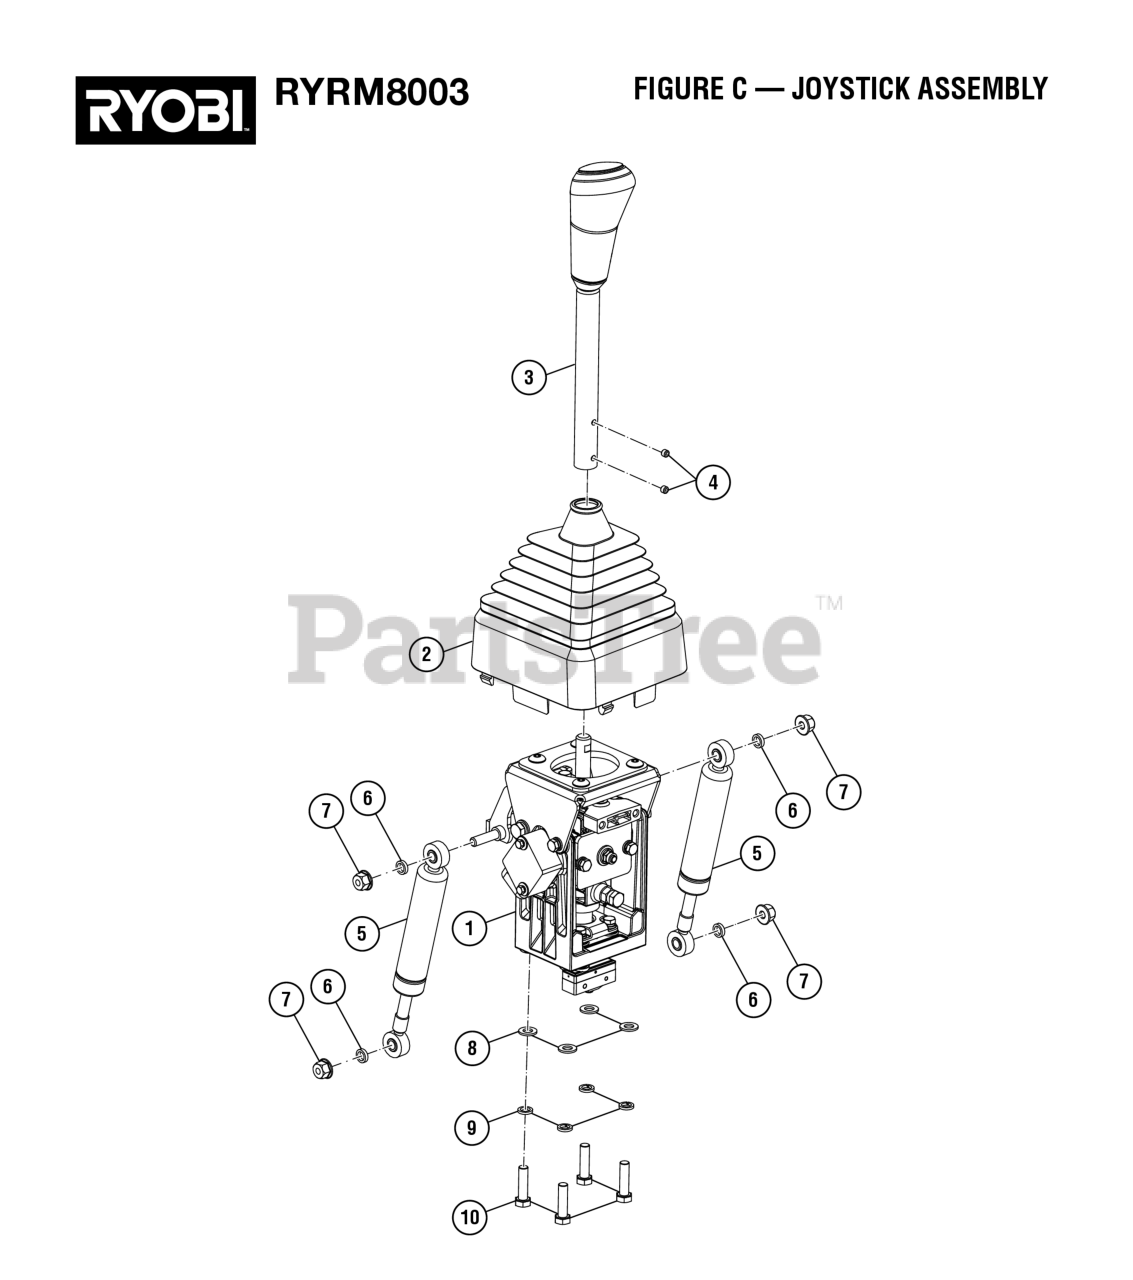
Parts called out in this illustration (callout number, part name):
1	Joystick Assembly
2	Joystick Bellow Assembly
3	Upper Joystick Handle
4	Set Screw (M6 x 8 mm)
5	Joystick Damper
6	Damper Bushing
7	Flange Nut (M8) (For Drive Motor Controller V)
8	Washer (OD16 x ID8.4 x 1.6t)
9	Lock Washer (OD9.8 x ID8.5 x 5t)
10	Screw (M8 x 30 mm, Hex Hd.)
